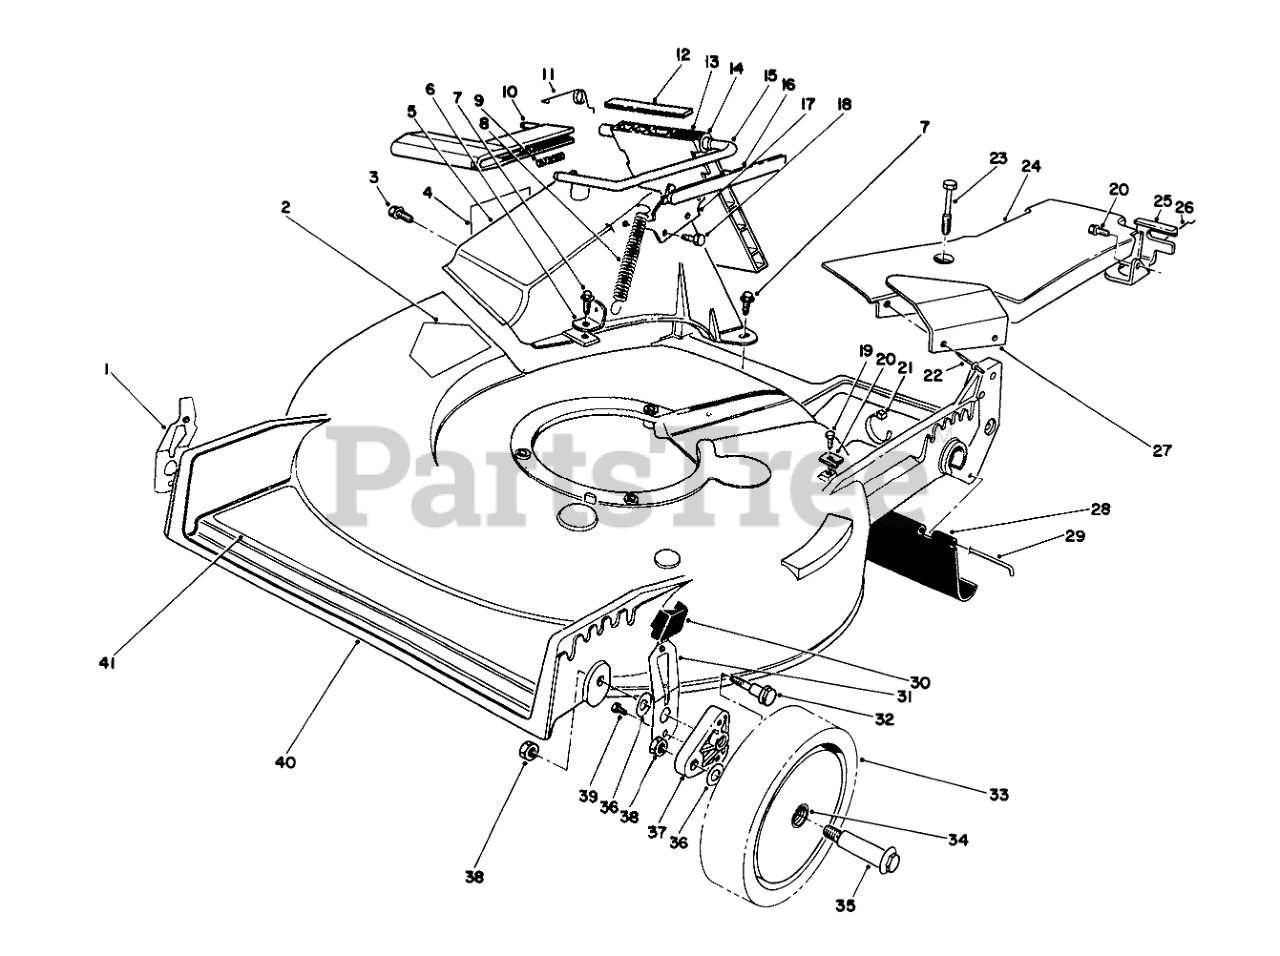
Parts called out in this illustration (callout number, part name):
1	RH SPRING ARM ASSEMBLY
2	DECAL-DANGER
3	SCREW AND WASHER ASM
4	DECAL - DANGER
5	DISCHARGE TUNNEL
6	Bracket-Spring
7	SCREW-HWH
8	SPRING-DOOR
9	Spring
10	Handle-Door
11	RETAINER-DOOR
12	Cover-Door
13	Door-Discharge
14	BUSHING-NYLON
15	Rod-Door
16	Cover-Handle
17	STOP LEVER SUB ASSEMBLY
18	SCREW-PLASTITE
19	SCREW-HWHTF
20	CLAMP-CABLE
21	TIE-CABLE
22	RIVET-HEAD, FLAT
23	SCREW-HHFTF
24	Cover-Belt (Incl. Ref. #22 & 27)
25	Bracket-Adj. Trac
26	RETAINER-CABLE
27	HEAT SHIELD
28	SHIELD-TRAILING
29	ROD-SHIELD
30	KNOB-ARM
31	LH SPRING ARM ASSEMBLY
32	SCREW-SHOULDER
33	Wheel & Tire Assembly (Incl. Ref. #34)
34	BUSHING
35	WHEEL BOLT
36	WASHER
37	ARM-PIVOT, FRONT
38	Nut
39	SCREW-HWH
40	Housing Assembly (Incl. Ref. #2, 7, & #6 on page 3)
41	DECAL - DECK
